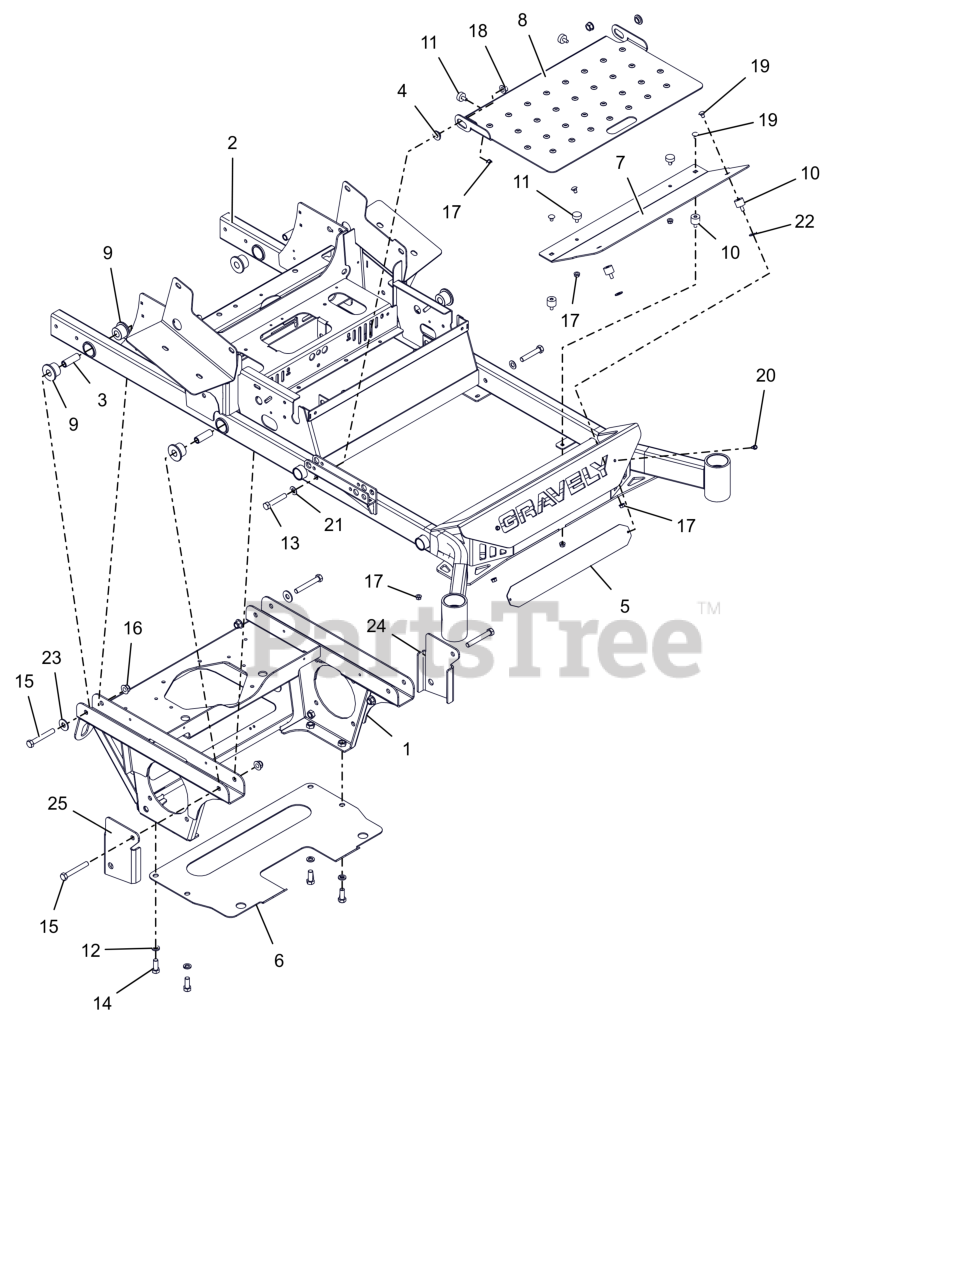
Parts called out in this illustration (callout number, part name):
1	PT200/400 AXLE/ENG FRM WMT-RED
2	52-60"PT200/400 FRAME W/DECALS
3	BSHG-SLV .50X.75X2.23
4	BSHG-FLG .515X.750X.310X1.120
5	BUMPER LOGO BACKING PLATE -BLK
6	PLATE-TRANSMISSION SKID
7	FOOTREST, (RED)
8	INSPECTION PANEL W/SAFE DECAL
9	BSHG-FLG .75X1.51X1.13X2.0 URE
10	BUMPER,STUD MNTD W/FEMALE INSR
11	BUMPER, RUBBER
12	WSHR,LK-REG .500X.125 ZCC
13	BLT,HEX .50-13X2.75 G5 ZCC
14	BLT,HEX .50-13X1.25 G5 ZCC
15	BLT, HEX .50-13X3.50 G5 ZCC
16	NUT,NYL-FLG .50-13 GF ZCC
17	NUT,SPNLK-FLG .31-18 G5 ZCC
18	NUT-LK-CTR-FLG .500-13 GG ZCC
19	BTL,RHSN .313-18 X 0.5 G5 ZCC
20	SCR-TAP .25-20X.50 HWH ZCC
21	WSHR, FLT .531X1.00X.063 ZCC
22	WSHR,FLT .375X.875X.083 ZCC
23	WSHR,FLT .563X1.375X.109 ZCC
24	STOP, DECK LH (BLACK)
25	STOP, RH DECK (BLACK)
